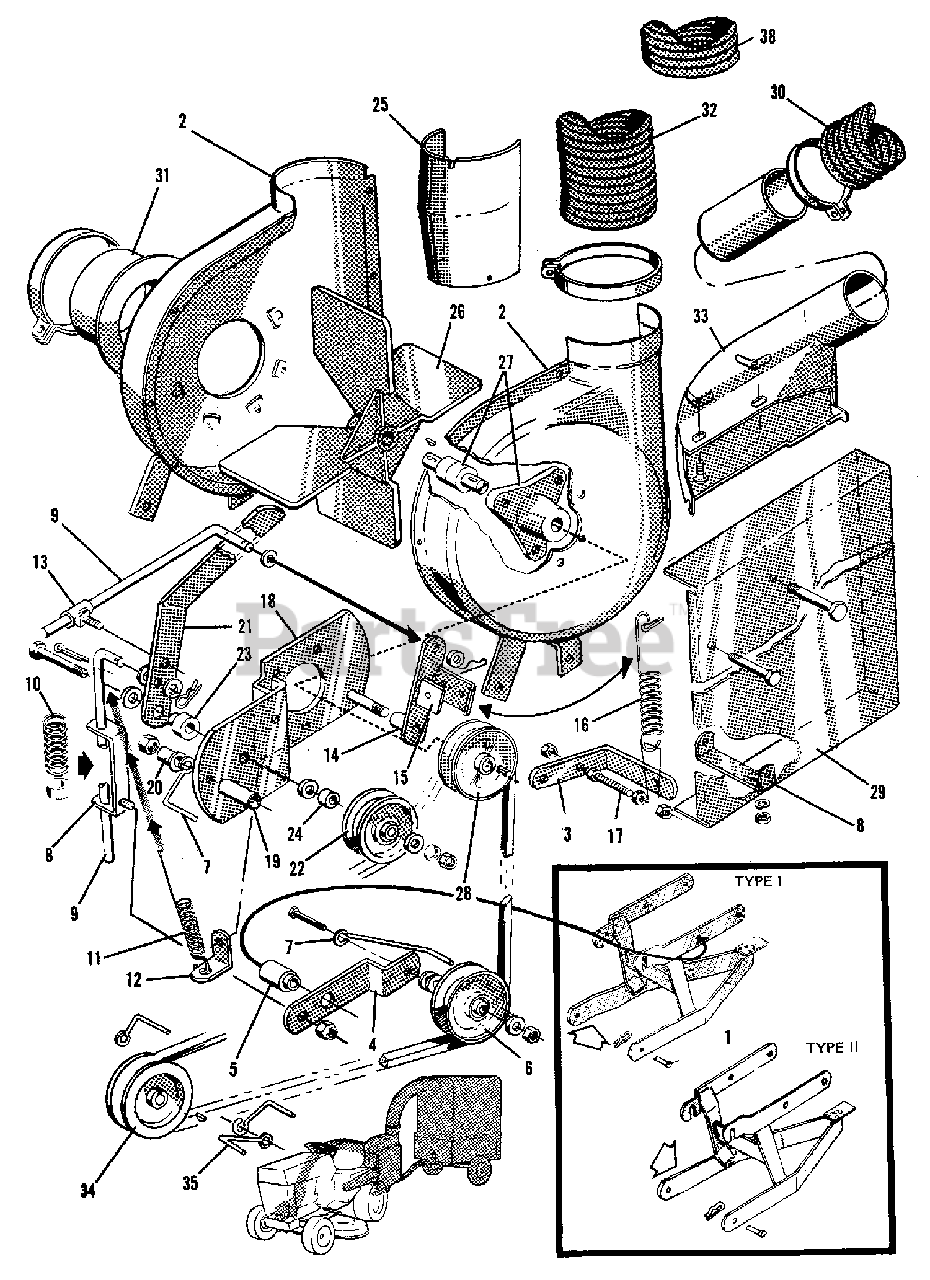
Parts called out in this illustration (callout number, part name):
1	SUPPORT ASSEMBLY, Blower Housing (Type 2)
1	SUPPORT ASSEMBLY, Blower Housing (Type 1)
1	CAPSCREW, 3/8NC x 1-1/4
1	LOCKWASHER, 3/8
1	NUT, 3/8NC
2	HOUSING ASSEMBLY, Inlet Half (L.H.)
2	HOUSING ASSEMBLY, Blower Half (R.H.)
2	CAPSCREW, 1/4NC x 1/2
2	LOCKWASHER, 1/4
2	NUT, 1/4NC
3	BRACKET, Cover
3	CAPSCREW, 5/16NC x 3/4
3	CAPSCREW, 3/8NC x 1-1/4
3	LOCKWASHER, 5/16
3	LOCKWASHER, 3/8
3	NUT, 5/16NC
3	NUT, 3/8NC
4	ARM, Idler Support
4	NUT, 5/16NC, Lock
5	PIVOT, Idler Arm
5	CAPSCREW, 3/8NC x 3
5	WASHER, 13/32 x 1-1/2 x 11 Ga
5	LOCKWASHER, 3/8
5	NUT, 3/8NC
6	PULLEY, Idler
6	CAPSCREW, 3/8NC x 1-3/4
6	WASHER, 13/32 x 7/8 x 14 GA
6	LOCKWASHER, 3/8
6	NUT, 3/8NC
7	STOP, Belt
7	LOCKWASHER, 5/16
7	NUT, 5/16
8	BRACKET ASSEMBLY, Support
8	CAPSCREW, 5/16NC x 3/4
8	LOCKWASHER, 5/16
8	NUT, 5/16NC
9	ROD, Control
9	PIN, Cotter
9	COLLAR, Set
9	SETSCREW, 1/4NC x 3/8, Square Head
9	CLIP, Spring
9	WASHER, 11/32 x 7/8 x 16 Ga
10	SPRING, Compression
11	SPRING, Tension
11	PIN, Cotter
12	BRACKET, Spring Mounting
12	CAPSCREW, 1/4NC x 1
12	WASHER, #10
12	LOCKWASHER, 1/4
12	NUT, 1/4NC
13	GUIDE ASSEMBLY, Rod
13	NUT, 5/16NC, Lock
14	LEVER ASSEMBLY, Brake
15	SCREW, #10NC x 5/8
15	LOCKWASHER, #10
15	NUT, #10NC
16	SPRING, Tension
16	PIN, Cotter
17	STUD, Spring Retaining
17	NUT, 3/8NC, Lock
17	LOCKWASHER, 3/8
17	NUT, 3/8NC
18	BRACKET ASSEMBLY, Idler Support
18	WASHER, 13/32 x 7/8 x 14 GA
18	NUT, 3/8NC, Lock
18	CAPSCREW, 3/8NC x 1
18	LOCKWASHER, 3/8
19	SPACER, Long
19	CAPSCREW, 5/16NC x 4
19	CAPSCREW, 5/16NC x 2-1/2
19	WASHER, 11/32 x 7/8 x 16 Ga
19	LOCKWASHER, 5/16
19	NUT, 5/16NC
20	SPACER, Short
21	LEVER, P.T.O.
22	PULLEY, Idler
22	CAPSCREW, 3/8NC x 2-1/2 (Type 1)
22	CAPSCREW, 3/8NC x 1-3/4 (Type 2)
22	WASHER, 13/32 x 1-1/2 x 11 Ga
22	WASHER, 13/32 x 7/8 x 14 GA
22	LOCKWASHER, 3/8
22	NUT, 3/8NC
23	SPACER, Pivot
25	DEFLECTOR
25	SCREW, #10NC x 3/8, Self-Tap
26	FAN ASSEMBLY, Blower
26	SETSCRE, 5/16NC x 1/2, Square Head
26	KEY, #9, Woodruff
27	FLANGE ASSEMBLY
28	PULLEY, Blower Drive
28	SETSCREW, 5/16NC x 5/16
28	KEY, #9, Woodruff
29	COVER, Belt Drive
30	HOSE, Intake
30	CLAMP, Hose
30	SCREW, 1/4NC x 2-3/4, Round Head
30	LOCKWASHER, 1/4
30	NUT, 1/4NC
31	FLANGE, Hose
32	HOSE, Exhaust
32	CLAMP, Hose
32	SCREW, 1/4NC x 2-3/4, Round Head
32	LOCKWASHER, 1/4
32	NUT, 1/4NC
33	ADAPTER ASSEMBLY, Vacuum Collector
33	NUT ASSEMBLY, Wing
33	BOLT, 3/8NC x 1
33	LOCKWASHER, 3/8
33	NUT, 3/8NC
34	PULLEY, P.T.O.
34	KEY, 3/16 x 3/16 x 1, Parallel
35	STOP, Belt
35	CASPCREW, 38NC x 1-1/4
35	WASHER, 13/32 x 7/8 x 14 Ga.
35	LOCKWASHER, 3/8
35	NUT, 3/8NC
36	PIN, Round Head
36	CLIP, Spring
37	V-BELT, Blower Drive (Type 1)
37	V-BELT, Blower Drive (Type 2)
38	HOSE, Extension
